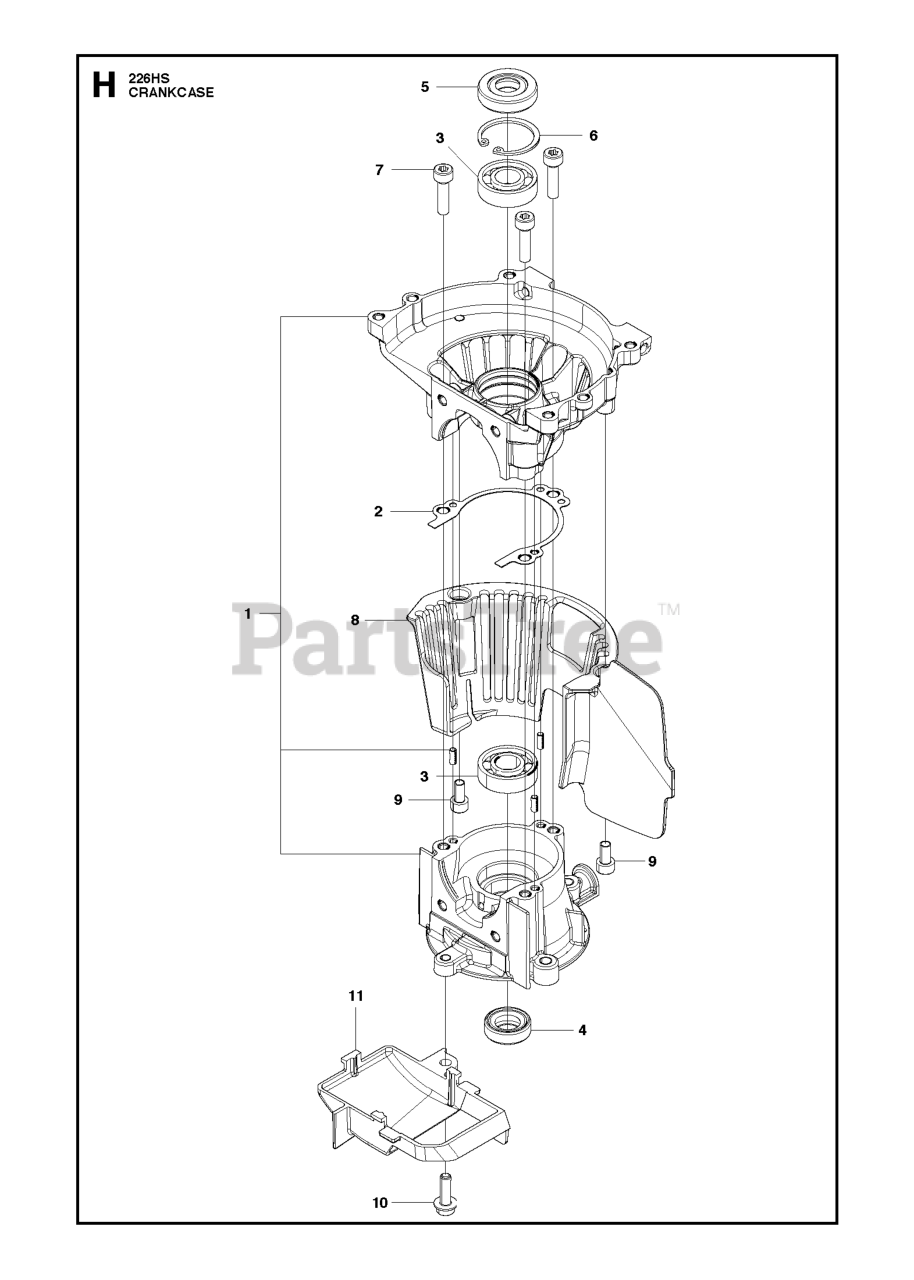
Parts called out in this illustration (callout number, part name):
1	CRANKCASE COMP
2	GASKET, CASE
7	BOLT
9	BOLT 08
